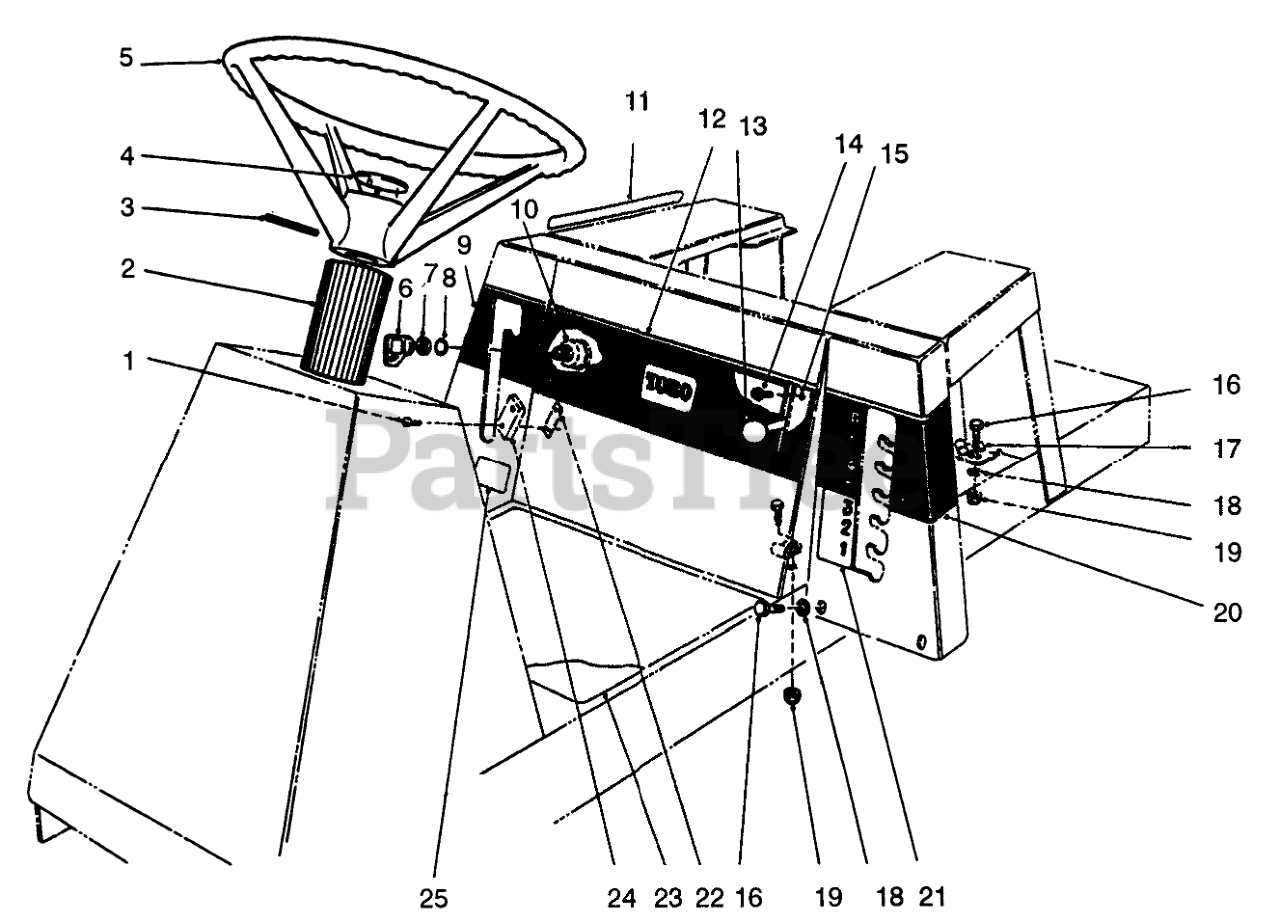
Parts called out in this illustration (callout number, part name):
1	SCREW-SPH
2	COVER-STEERING SHAFT
3	PIN-ROLL
4	STEERING WHEEL INSERT
5	Assy.-Wheel, Steering (Incl. Ref. #4)
6	KEY-IGNITION
7	NUT-HH
8	WASHER-TOOTH, INTERNAL
9	DECAL-UPPER DECK ENGAGE
10	Switch-Ignition (Incl. Ref. #6-8)
11	DECAL - SHIFT PATTERN
12	DECAL-FRT SEAT CONTROLS
13	KNOB-CONTROL
14	SCREW-HWHTF
15	Control-Throttle (Incl. Ref. #13)
16	SCREW-HH
17	CLAMP
18	WASHER-PLAIN
19	NUT-LOCK, NI
20	DECAL - UPPER HOC
21	DECAL - LOWER HOC
22	NUT-SPEED
23	INSTRUCTION DECAL
24	SWITCH-MICRO
25	DECAL-LOWER DECK ENGAGE
